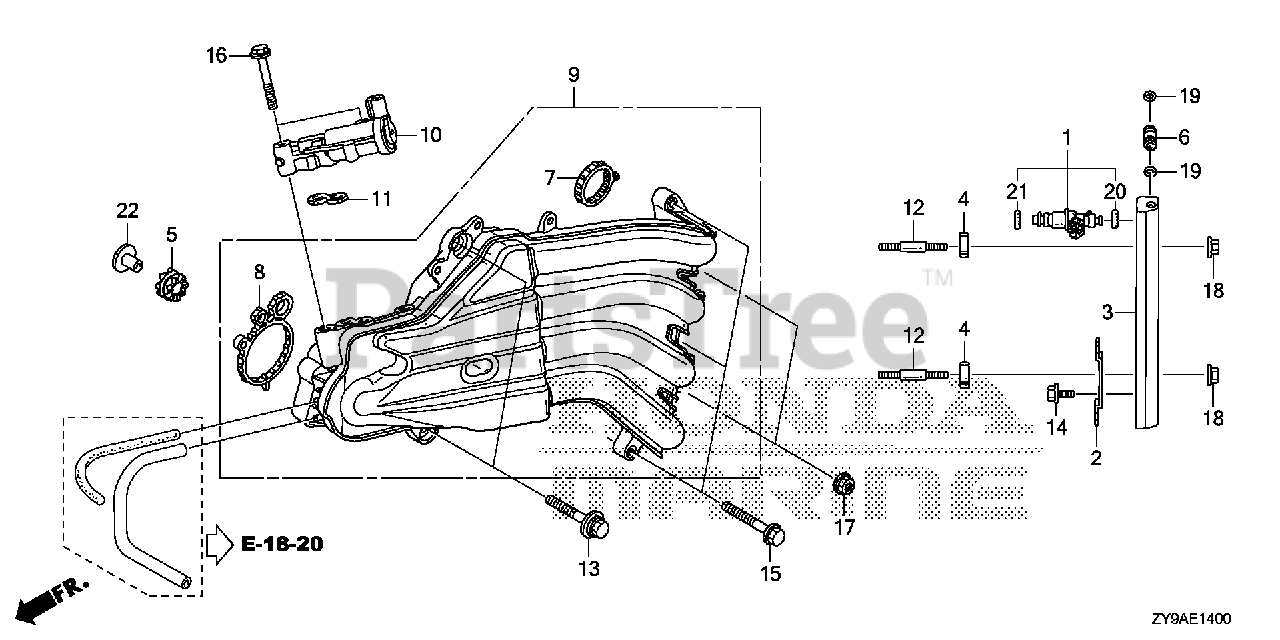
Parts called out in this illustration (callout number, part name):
1	INJECTOR ASSY., FUEL
2	CLIP, INJECTOR
3	LINE, FUEL
4	INSULATOR, FUEL PIPE
5	GROMMET, VAPOR SEPARATOR
6	JOINT, FUEL PIPE
7	GASKET, IN. MANIFOLD
8	GASKET, THROTTLE BODY
9	MANIFOLD, INLET
10	VALVE ASSY., ELECTRONIC AIR CONTROL
11	GASKET, ELECTRONIC AIR CONTROL VALVE
12	BOLT, STUD (6X40)
13	BOLT-WASHER (8X35)
14	BOLT, FLANGE (6X10)
15	BOLT, FLANGE (8X35)
16	BOLT, FLANGE (8X45)
17	NUT, FLANGE (8MM)
18	NUT, FLANGE (6MM)
19	O-RING (7.8X1.9) (ARAI)
20	O-RING (7.47X3.6)
21	O-RING (7.45X3.61) (NOK)
22	COLLAR (8.5X14.5)
